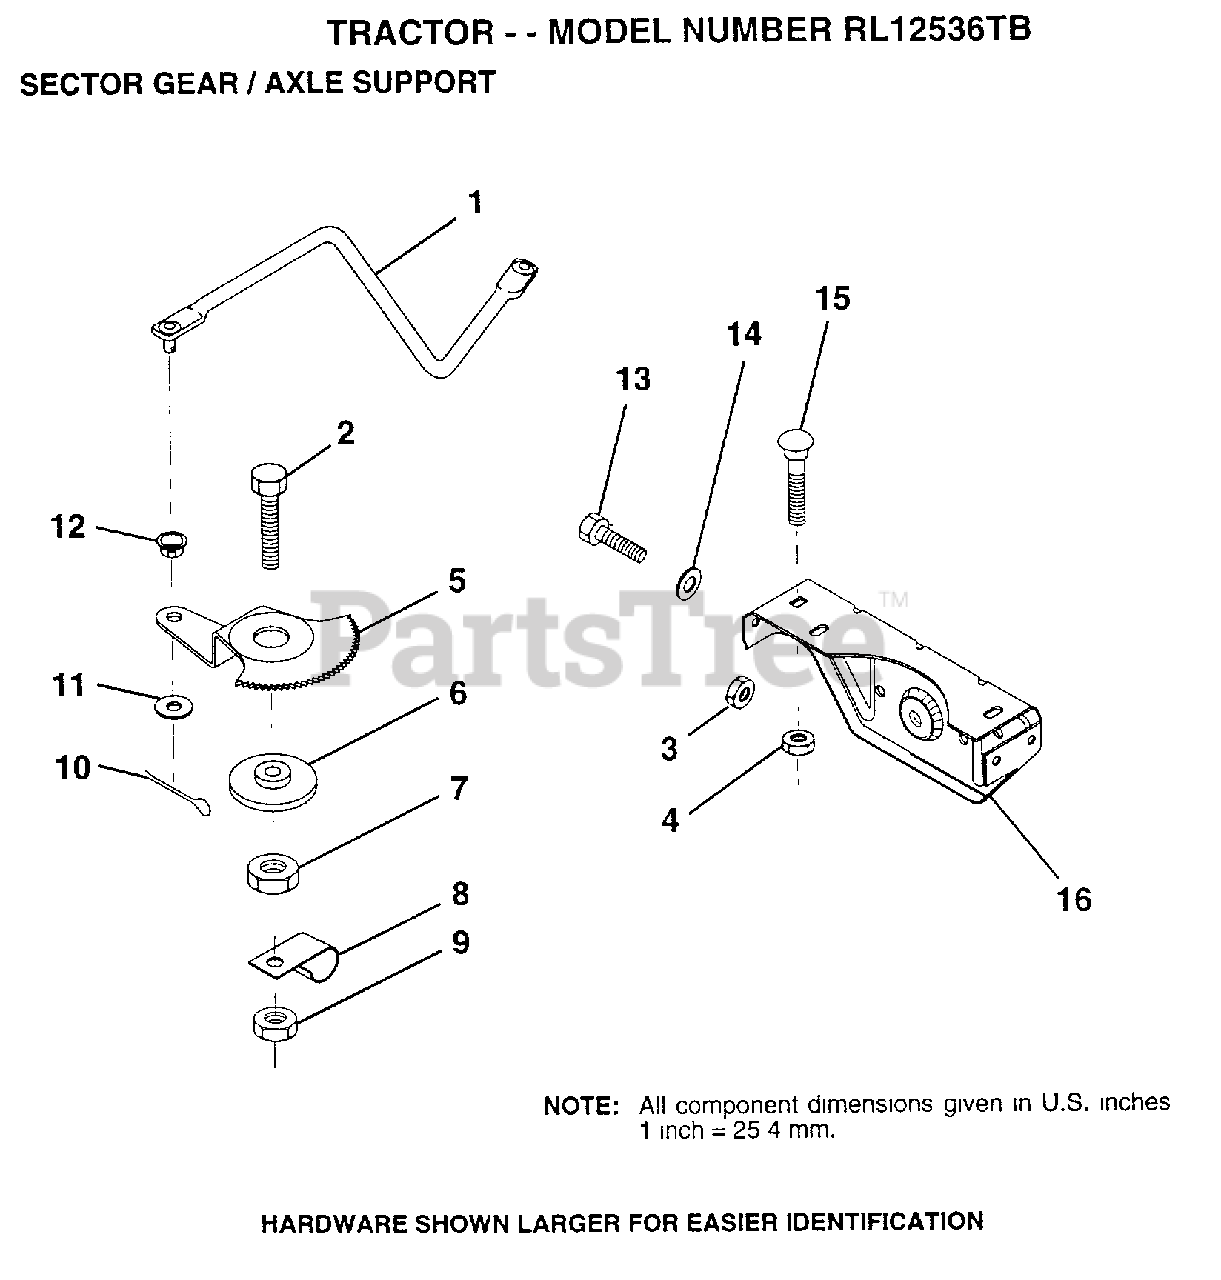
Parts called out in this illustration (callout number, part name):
1	DRAG LINK
2	"BOLT,HEX"
5	GEAR SECTOR
6	BUSHING
7	NUT
8	CLIP INSULATOR
9	NUT LTV
10	COTTER PIN
11	WASHER
12	BUSHING.DRAGLINK
13	BOLT
14	WASHER
15	BOLT
16	SUPT AXLE FRONT
